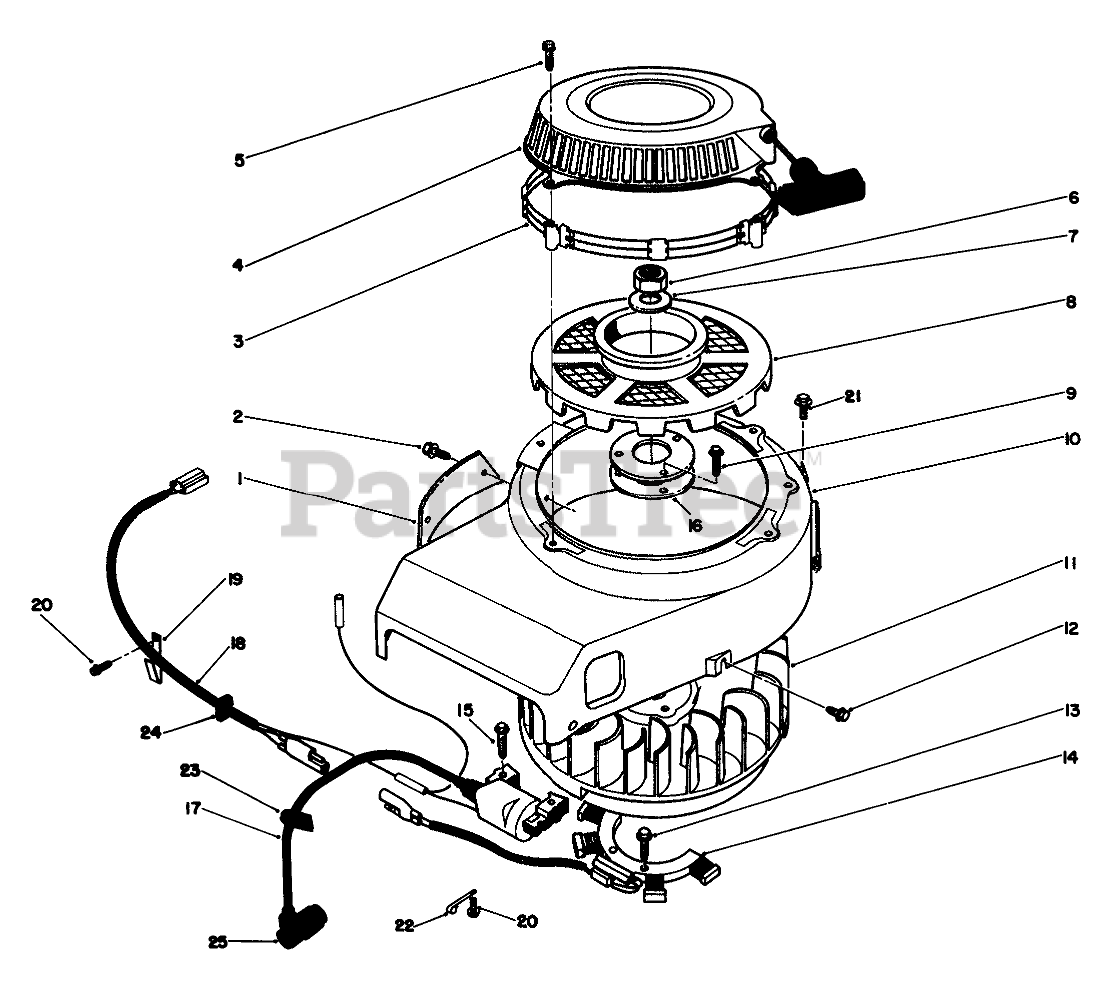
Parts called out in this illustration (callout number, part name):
1	Cover
4	Recoil Starter ASM
5	Bolt-Flanged (6X35)
9	Bolt-Flanged (8X12)
10	Housing-Fan
11	Flywheel
12	BOLT-FLANGED (6X10)
15	Bolt
17	Coil
19	Clamp
20	Bolt-Flanged (6X10)
21	Bolt-Flanged (6X14)
25	Cap-Spark
